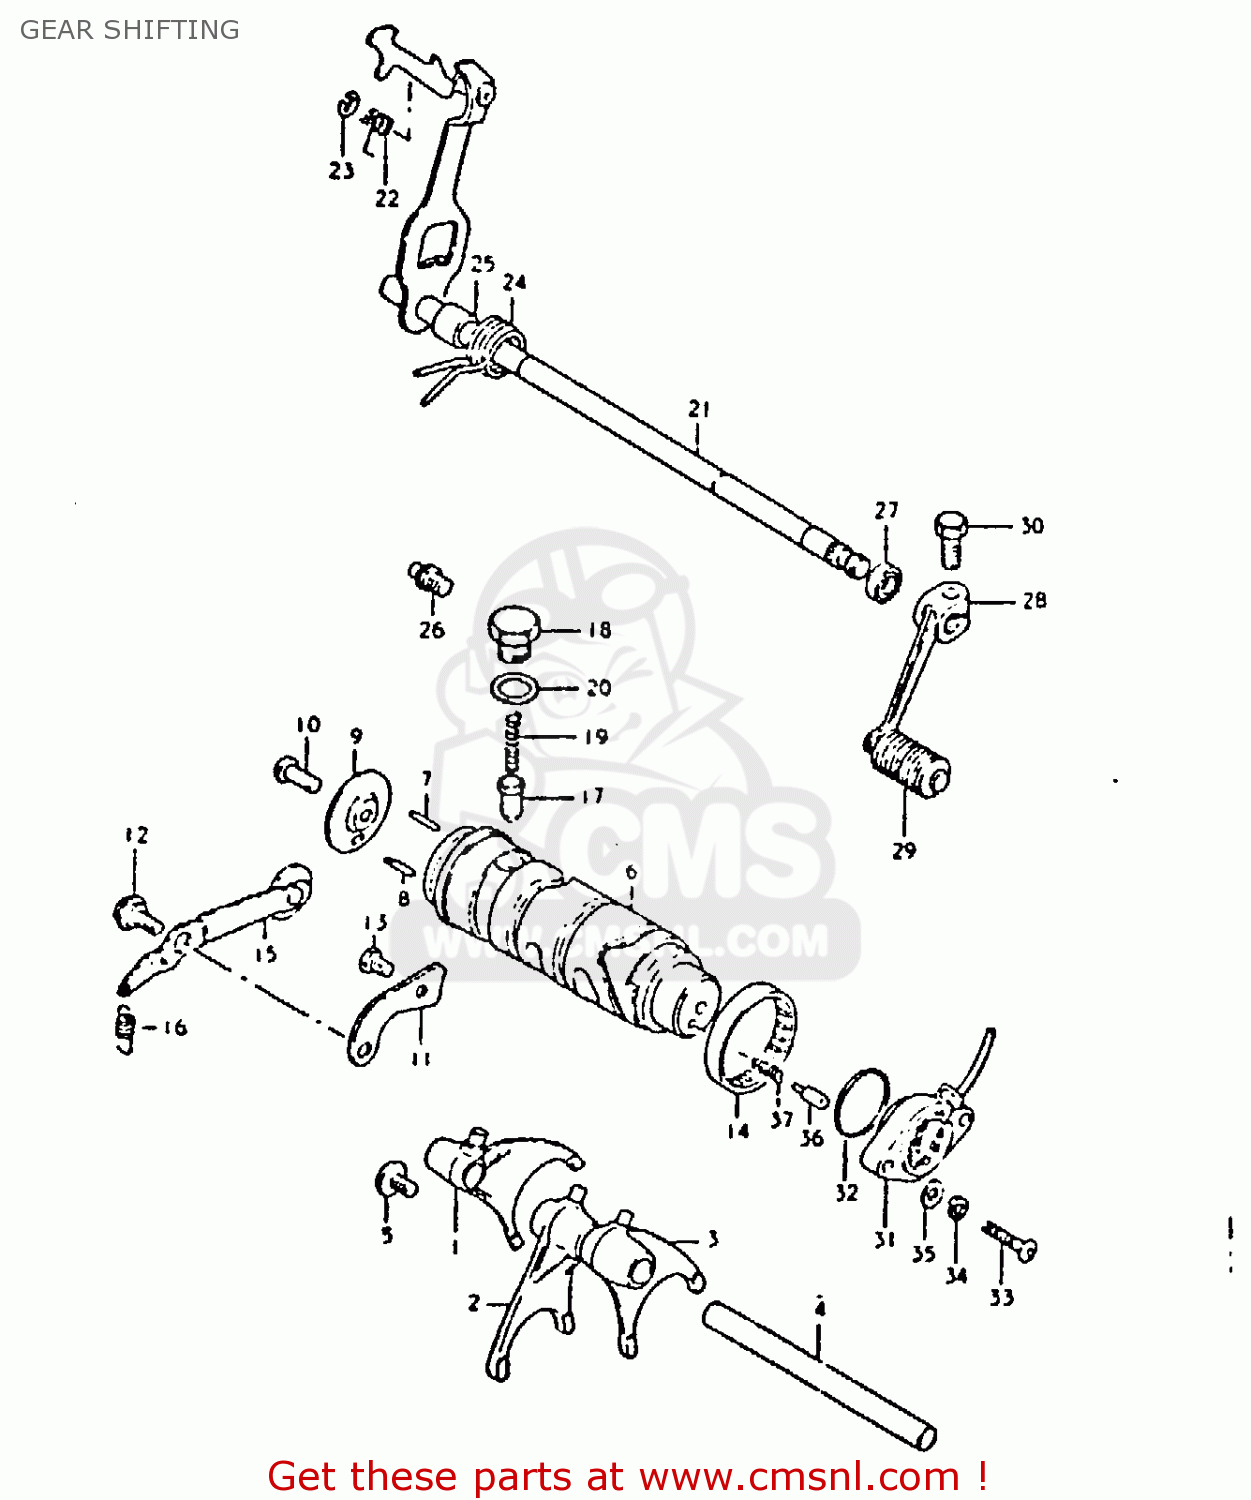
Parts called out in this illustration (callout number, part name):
1	FORK,GEAR SHIFT NO.1
2	FORK,GEAR SHIFT NO.2
3	FORK,GEAR SHIFT NO.3
4	SHAFT,GEAR SHIFT FORK
5	SCREW
6	CAM,GEAR SHIFT
7	PIN(4X18.5)
8	PIN
9	RETAINER,GEAR SHIFT CAM DR PIN
10	SCREW
11	GUIDE,GEAR SHIFTING CABLE
12	BOLT
13	BOLT, UPPER
14	BEARING(40X47X12)
15	STOPPER,GEAR SHIFTING
16	SPRING
17	STOPPER,GEAR SHIFT CAM NO.2
18	HOLDER,GEAR SHIFT CAM STOP SPR
19	SPRING
20	GASKET(14X19.2X2) (NAS)
21	SHAFT,GEAR SHIFT
22	SPRING
23	E RING
24	SPRING
25	SPACER(12X20X15.3)
26	STOPPER,GEAR SHIFT CAM
27	OIL SEAL
28	LEVER ASSEMBLY,GEAR SHIFTING
29	RUBBER,GEAR SHIFT PEDAL
30	BOLT
31	TERMINAL BASE,NEUTRAL SWITCH
32	O-RING (D:2.4 ID:26.2)
33	SCREW 5X20
34	LOCK WASHER
35	WASHER
36	PIN(5X15.5)
37	SPRING
